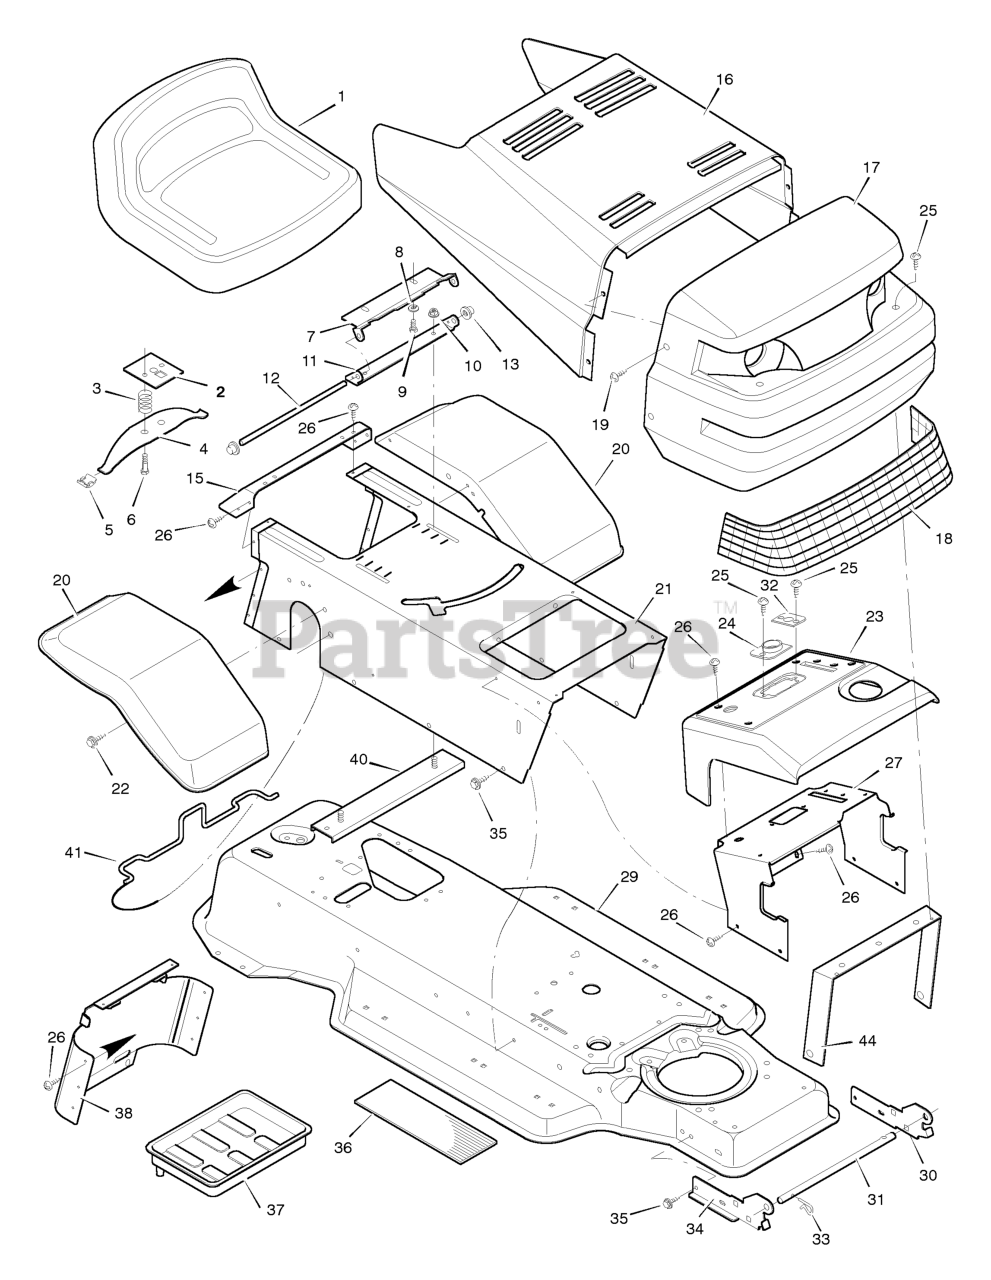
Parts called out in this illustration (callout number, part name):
2	Plate Assembly, Switch
3	Spring, Compression
4	Spring, Seat
5	Glide, Spring
6	Bolt, Shoulder
7	Support, Seat
8	Lockwasher
9	Bolt, Hex
10	Locknut, Flange
11	Bracket, Pivot
12	Rod, Pivot
13	Cap, Push On
15	Fender, Apron
17	Grille Assembly
21	Console Assembly
23	Dash Panel
24	Bearing, Steering
26	Screw
27	Support, Dash
29	Frame Assembly
30	Bracket, Left Grille
31	Rod, Pivot
32	Bearing
33	Pin, Hair
34	Bracket, Right Grille
37	Tray, Battery
38	Cap, Console
39	Bolt
40	Channel Assembly
41	Clamp, Battery
44	Brace, Grille
